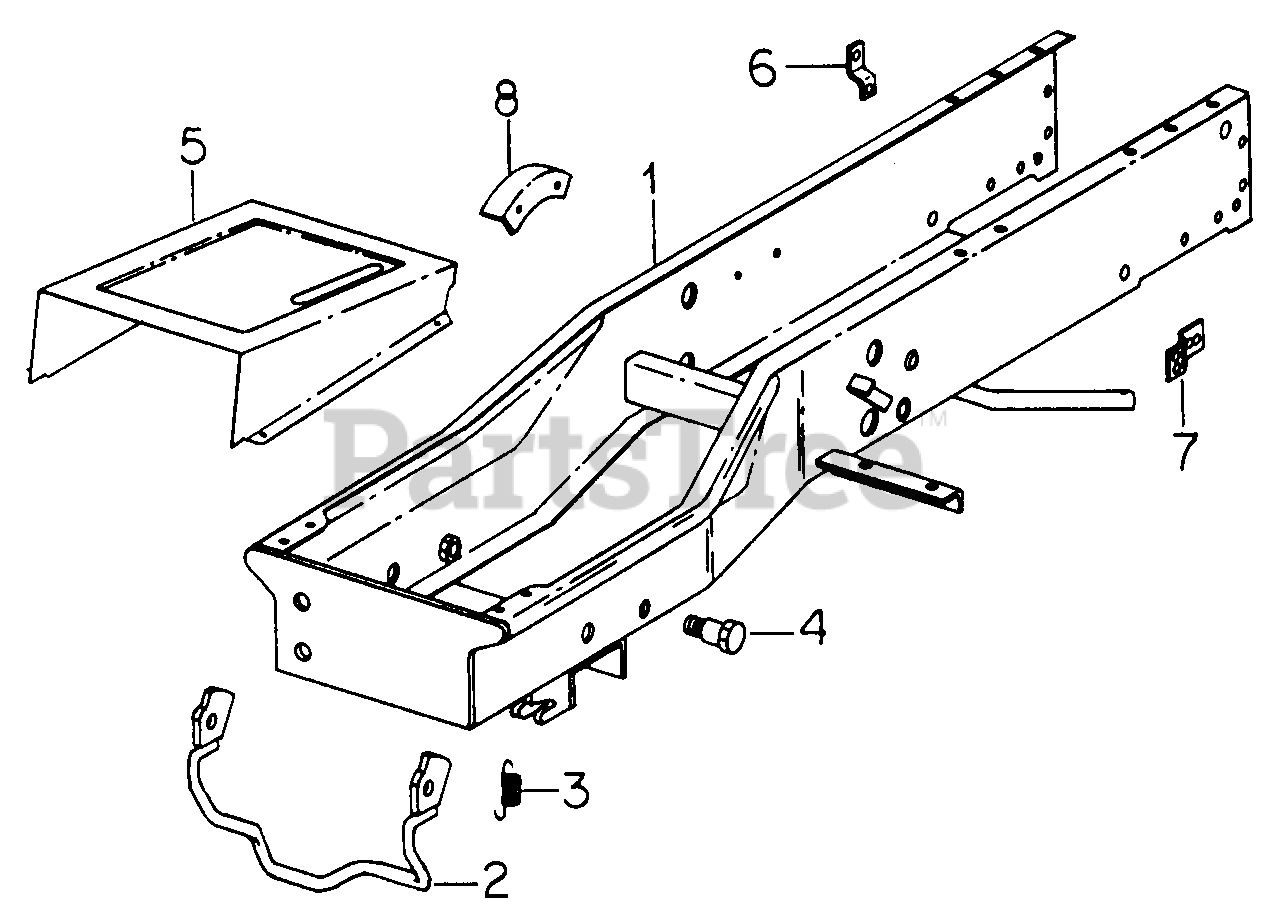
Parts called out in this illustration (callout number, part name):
3	Spring, Latch
4	Bolt, Implement Mtg Shoulder
5	Cover w/Product Graphic
6	Not used in this application
7	Not used in this application
8	Bracket, Indicator
